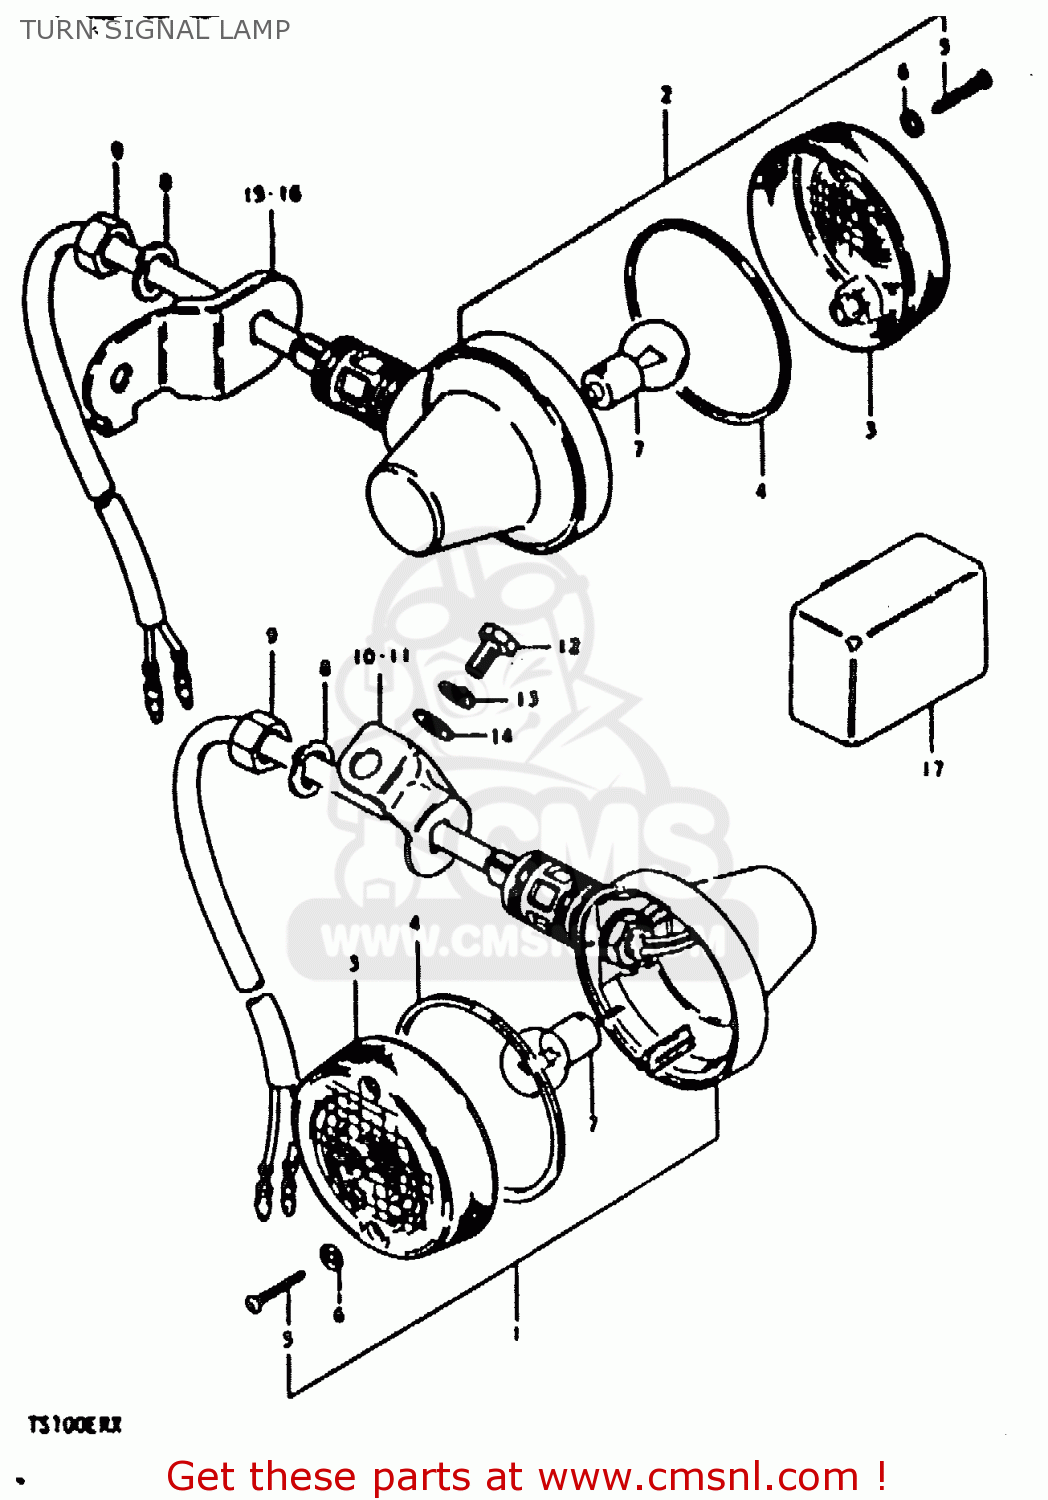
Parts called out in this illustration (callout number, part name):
1	LAMP, REAR TURN SIGNAL
2	LAMP, REAR TURN SIGNAL
3	LENS
4	GASKET
5	SCREW TAPP.
6	GASKET (NAS)
7	BULB(6V8W,STANLEY,A4115)
8	WASHER,LOCK 12
9	NUT
10	BRACKET,TURNSIGNAL LAMP,R
11	BRACKET,TURNSIGNAL LAMP,L
12	BOLT
13	LOCK WASHER
14	WASHER
15	BRACKET,REAR TURN SIGNAL
16	BRACKET,REAR TURN SIGNAL
17	RELAY, TURN SIGNAL
